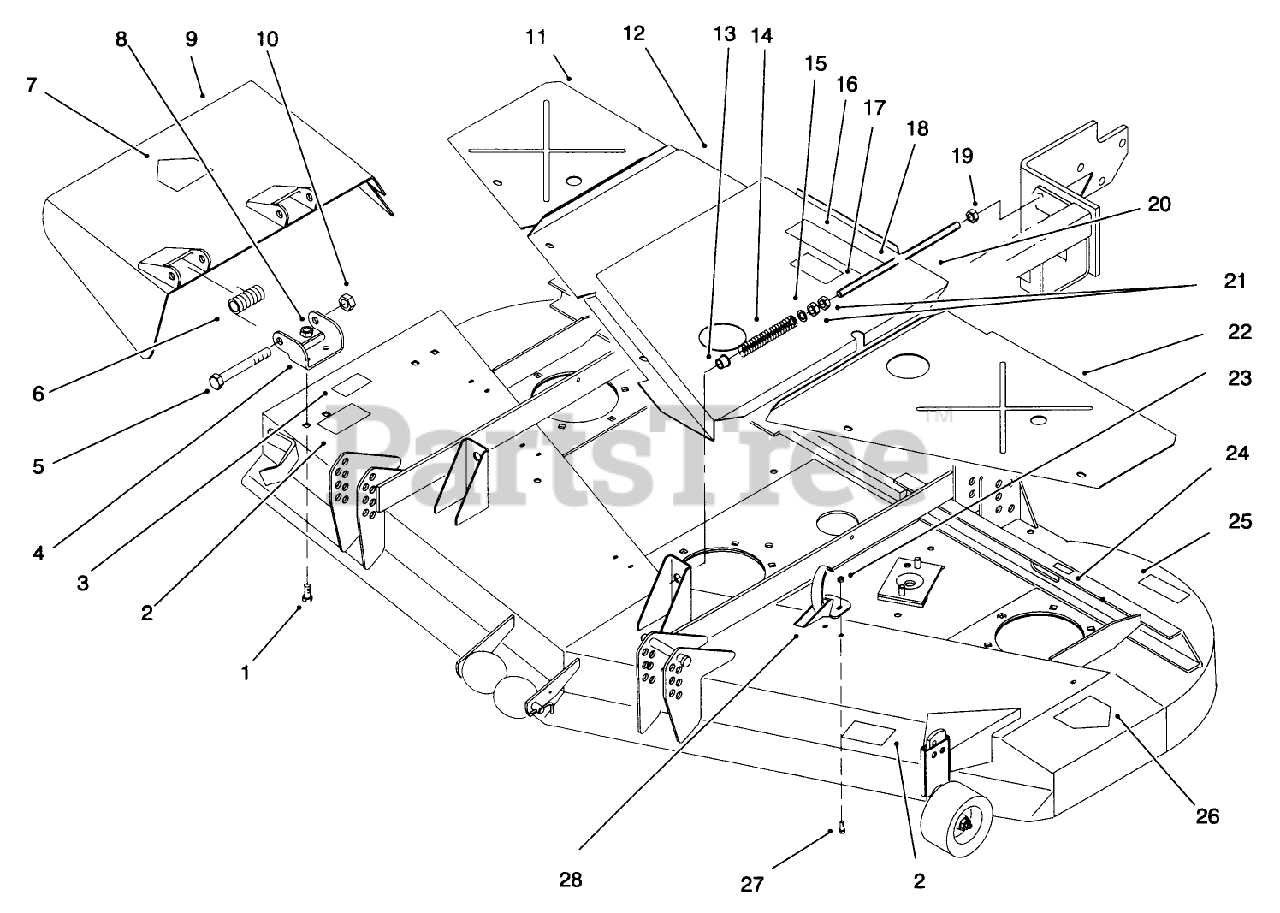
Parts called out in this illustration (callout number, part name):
1	SCREW-CARR
2	DECAL-DANGER, THROWN OBJECT
3	DECAL-DANGER
4	Bracket-Hinge
5	SCREW-HH
6	SPRING
7	DECAL-DANGER
8	NUT-HHF, WHIZ
9	Deflector Assembly (Incl. Ref.#7)
10	NUT-HEX
11	Cover-Deck R.H.
12	Cover-Deck, Center R.H.
13	BUSHING-FLANGE
14	SPRING
15	WASHER
16	DECAL-PROLINE
17	DECAL
18	ADJUSTING SHAFT
19	NUT-LOCK, NI
20	Cover-Deck, Center L.H.
21	NUT-JAM
22	Cover-Deck L.H.
23	NUT-LOCK, FLANGE
24	DECAL-DANGER
25	DECAL-TORQUE
26	DECAL-DANGER
27	SCREW-HWH
28	CLAMP-SLOTTED
